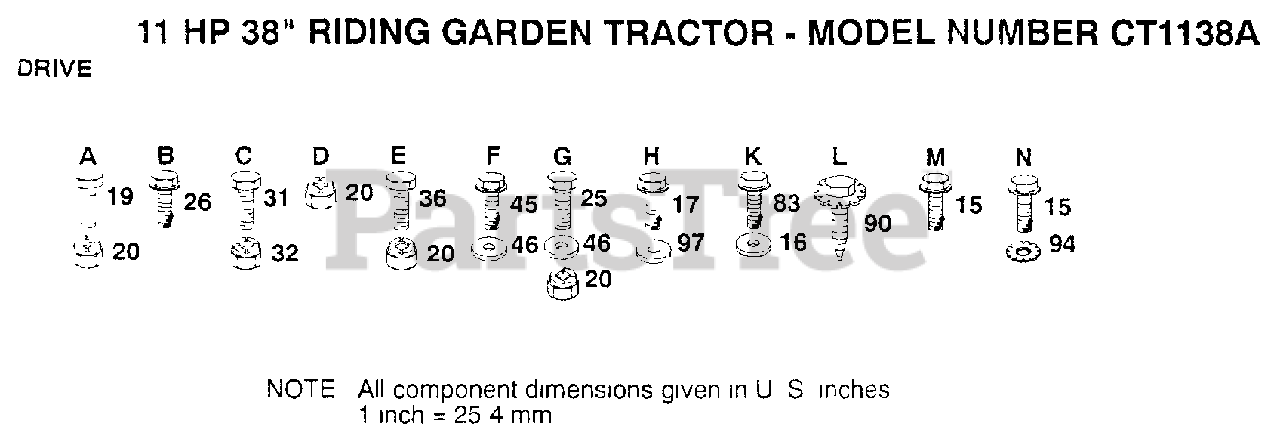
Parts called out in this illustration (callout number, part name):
15	SCREW
16	LOCKWASHER
17	"BOLT,HEX"
19	BOLT
25	BOLT
26	SCREW
31	BOLT
45	SCREW
46	WASHER
83	WASHER
94	LOCKWASHER
97	WASHER
